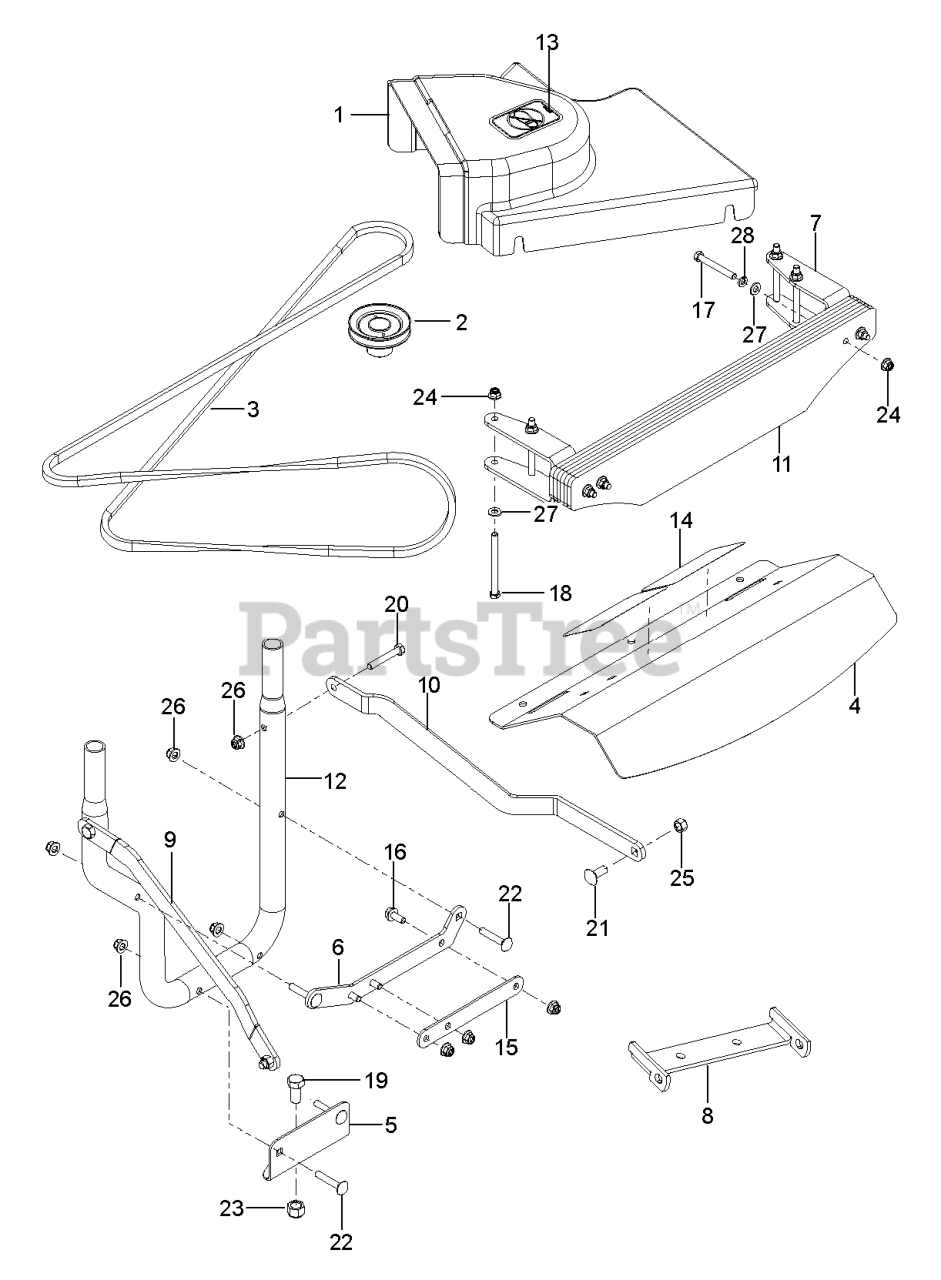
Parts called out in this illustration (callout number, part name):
1	SHIELD, BELT, 52"
2	PULLEY, 52"
3	BELT, 48/52"
4	FOOTPLATE.ORANGE.2013
5	MOUNT, HITCH, LOWER
6	BRKT, SUPPORT, BLK
7	BRACKET, WEIGHT, BLK
8	BRACKET, CHUTE BLK
9	STRAP.RT.BLACK
10	STRAP.LH.BLACK
11	WEIGHT PLATE, BLACK
12	MOUNT.TUBE.COLLECTIONS
13	DECAL, NO STEP
15	SPACER, PLATE, BLK
16	HHFS 5/16-18 X 3/4
17	HCS 3/8C X 3
18	TAPBOLT 3/8C X 4 1/2
19	HHCS 1/2-13 X 1
20	HCS 5/16-18X2
21	RHSNB 3/8C X 1
22	RHSNB 5/16-18X1 3/4
23	NUT 1/2-13 HEX NYLOC ZD
24	NUT 3/8-16 HEX FLG NYLOC ZD
25	NUT 3/8-16 NYLOC
26	5/16-18 NYLOC FLANGE NUT
27	WASHER 3/8 SAE FLAT
28	SLW 3/8 STD
